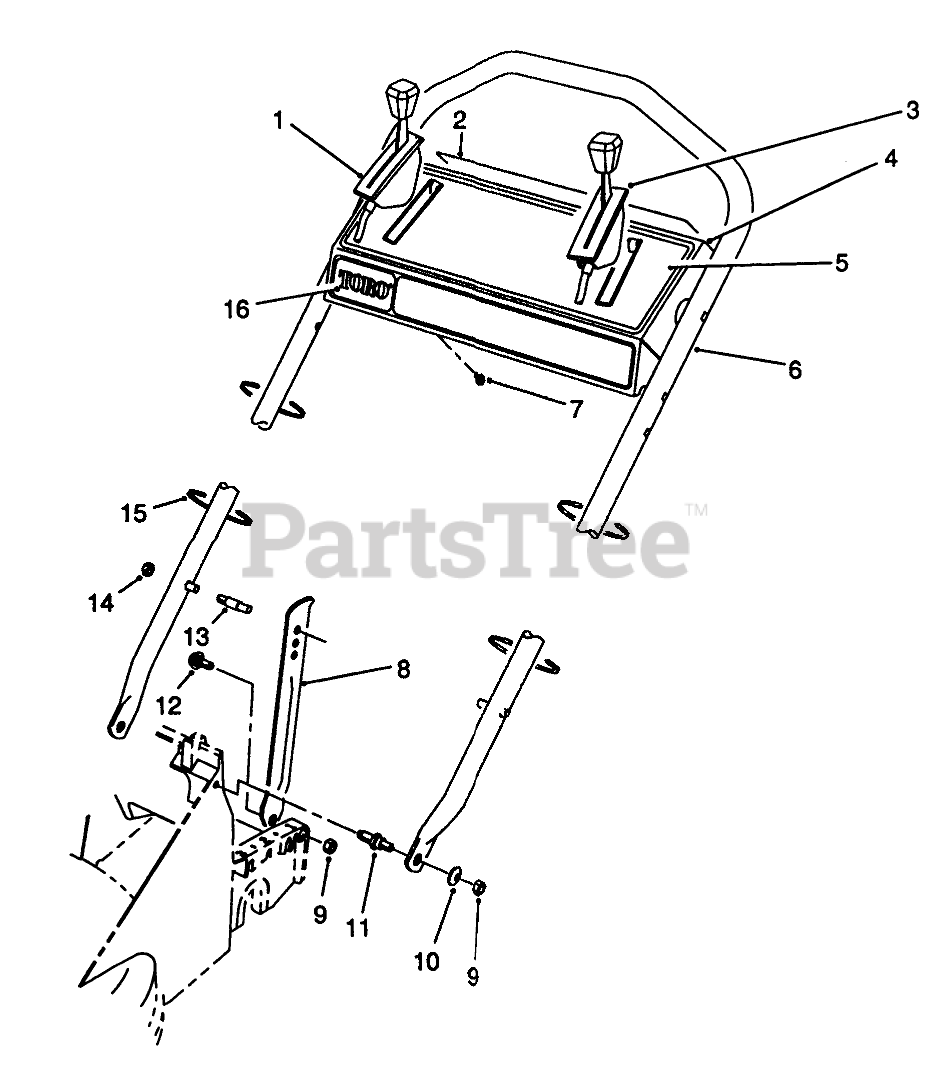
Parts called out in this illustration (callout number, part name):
1	Control-Ground Speed Bend Type #3 Sheath Lg. 51-1/4" Wire Lg. 2-1/8"
2	DECAL-PANEL, DANGER
3	Control-Throttle Bend Type #1 Sheath Lg. 44-1/2" Wire Lg. 2-3/16"
4	Control Panel Assembly (Incl. Ref . #2, 5 & 16)
5	Decal-Instruction
6	HANDLE
7	SCREW-HWHTF
8	HANDLE LATCH
9	NUT-LOCK, NI
10	WASHER-PLAIN
11	SCREW - SHOULDER STUD
12	SCREW - SHOULDER
13	HANDLE PIN
14	NUT-LOCK, NI
15	TIE-CABLE
16	DECAL - TORO PANEL
